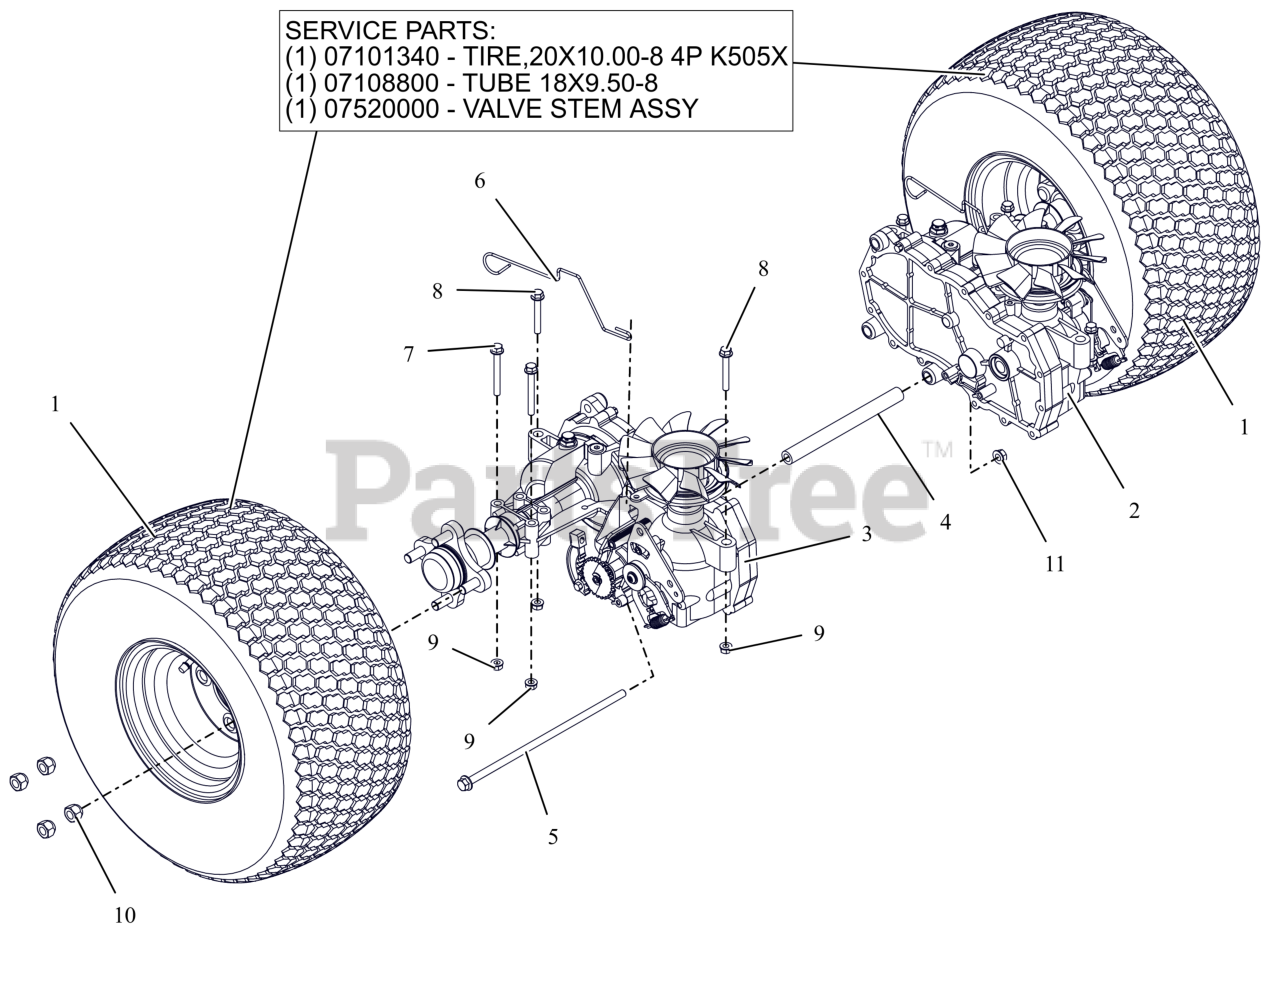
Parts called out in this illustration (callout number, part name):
1	ASSM TIRE\WHEEL, 20 X 10 -8
1	LAWN TIRE REAR, 4 PLY kK505 20/10.00-8
1	VALVE STEM ASS'Y
1	TIRE TUBE 18/6.50/8.50/9.50-8, 20/8.00/10.00-8 4 PLY TR13 STRAIGHT VALVE
2	TRANSAXLE- EZT - LH
3	TRANSAXLE- EZT-RH
4	TUBE, TRANSAXLE BRACE 8.18LG
5	BLT,HEX-FLG .38-16X11.5 G5 ZCC
6	WIRE- DUMP VALVE LEVER
7	BLT,HEX-FLG .31-18X2.75 G5 ZCC
8	BLT,HEX-FLG .31-18X2.25 G5 ZCC
9	NUT,LK-CTR-FLG .31-18 GF ZCC
10	NUT, WHEEL .50-20 ZCC
11	NUT-LK-CTR-FLG .375-16 GF ZCC
